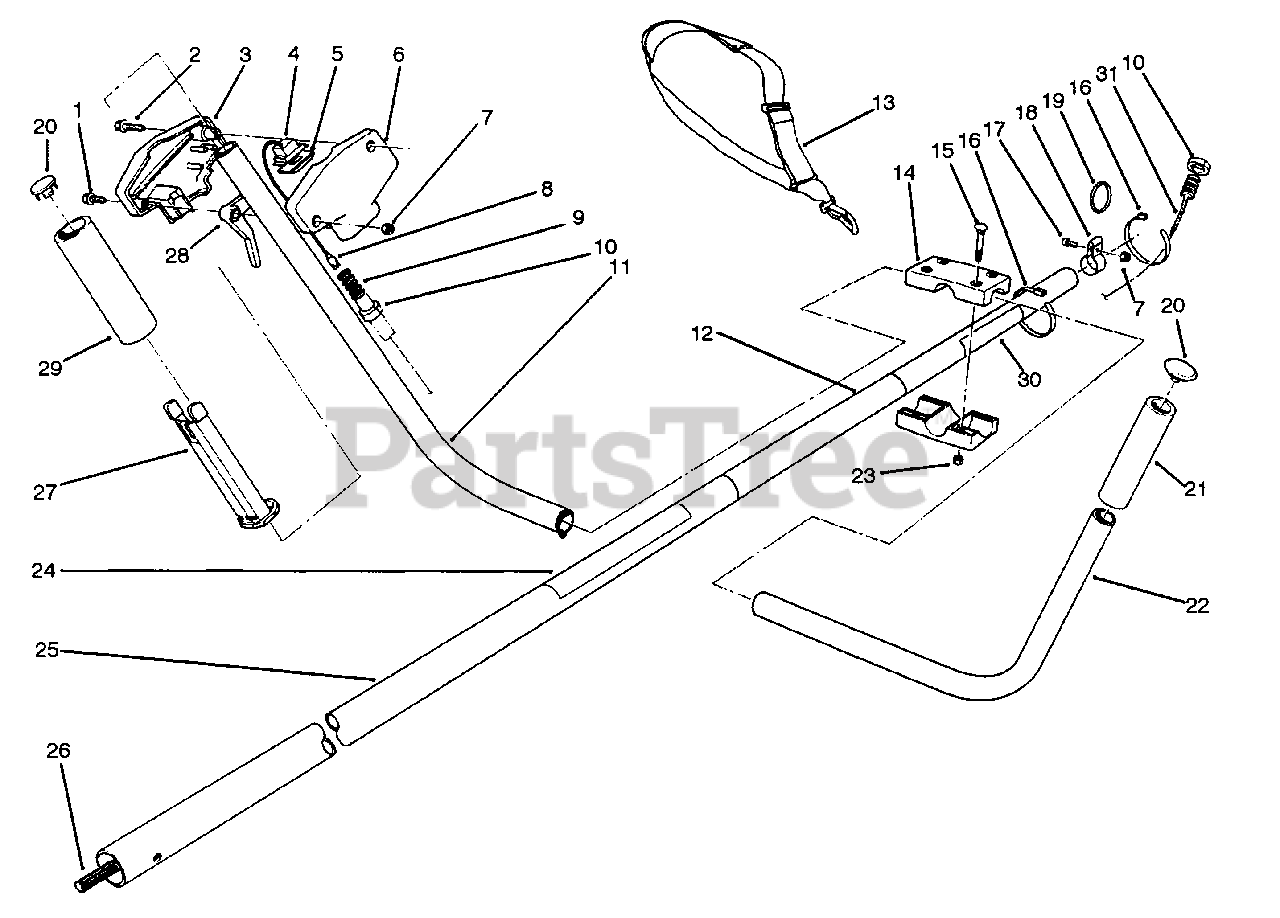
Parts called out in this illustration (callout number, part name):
1	Screw-Hex. Hd.
2	Screw-Hex. Hd.
3	Housing-R.H.
5	Cap-Switch
6	Housing-L.H.
7	Nut-Lock
9	Cover-Cable
11	Tube-Handle R.H.
12	Decal-Danger
13	Harness-Shoulder
14	Clamp-Bull Horn
15	Bolt-Carriage
16	Tie-Cable
17	Screw-Machine Hd.
18	Clamp-Harness
19	Ring-Harness
20	Plug-Button
21	Grip-Handle L.H.
22	Tube-Handle L.H.
23	Nut-Lock
24	Decal-TC 5010
25	Tube Assembly
26	Shaft-Drive
28	Lever-Throttle
29	Grip-Handle L.H.
30	Decal-Instruction
31	Cable-Throttle
